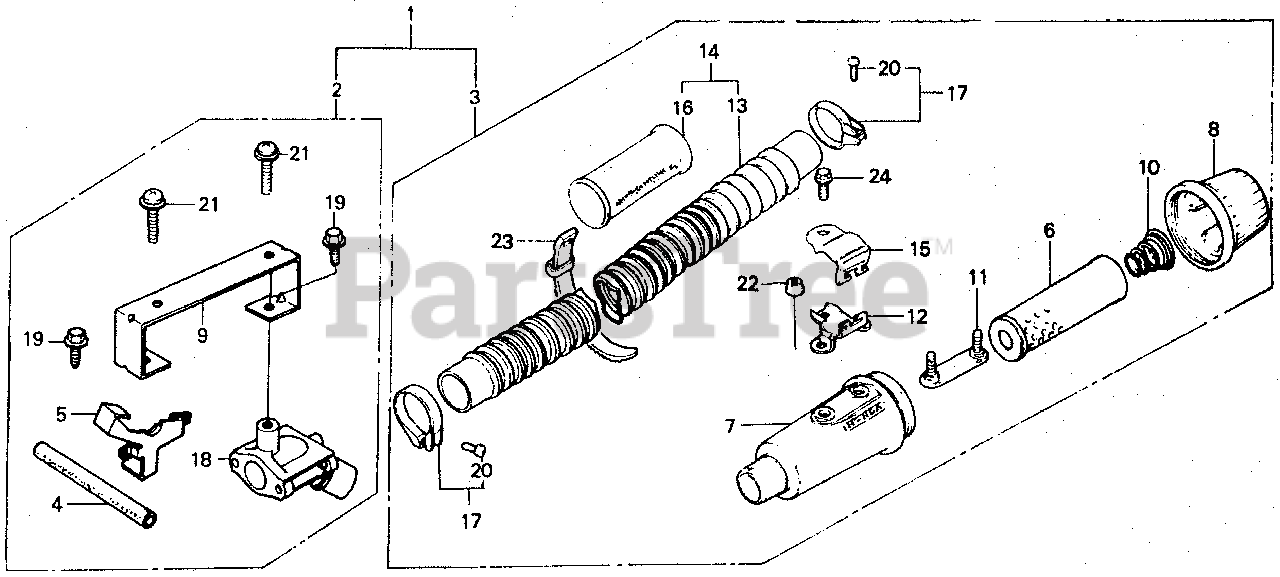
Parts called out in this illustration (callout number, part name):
1	AIR CLEANER KIT, SNORKEL JOINT
2	JOINT KIT, SNORKEL AIR CLEANER (N/A: SEE COMPONENTS)
3	AIR CLEANER KIT, SNORKEL (N/A: SEE COMPONENTS)
4	TUBE, BREATHER
6	ELEMENT, AIR CLEANER
7	HOUSING, AIR CLEANER
8	CAP, AIR CLEANER
9	STAY, CARBURETOR COVER
10	SPRING, SETTING
11	PLATE, AIR CLEANER SETTING
12	BRACKET A, AIR CLEANER
13	HOSE, AIR CLEANER
15	BRACKET B, AIR CLEANER
17	BAND, AIR CLEANER CONNECTING TUBE (34)
18	JOINT, TUBE CONNECTING
19	BOLT, FLANGE (6X12) (CT200)
20	SCREW, PAN (4X25)
21	SCREW-WASHER (6X25)
22	NUT, FLANGE (6MM)
23	BAND B3, WIRE
24	BOLT, FLANGE (6X16)
